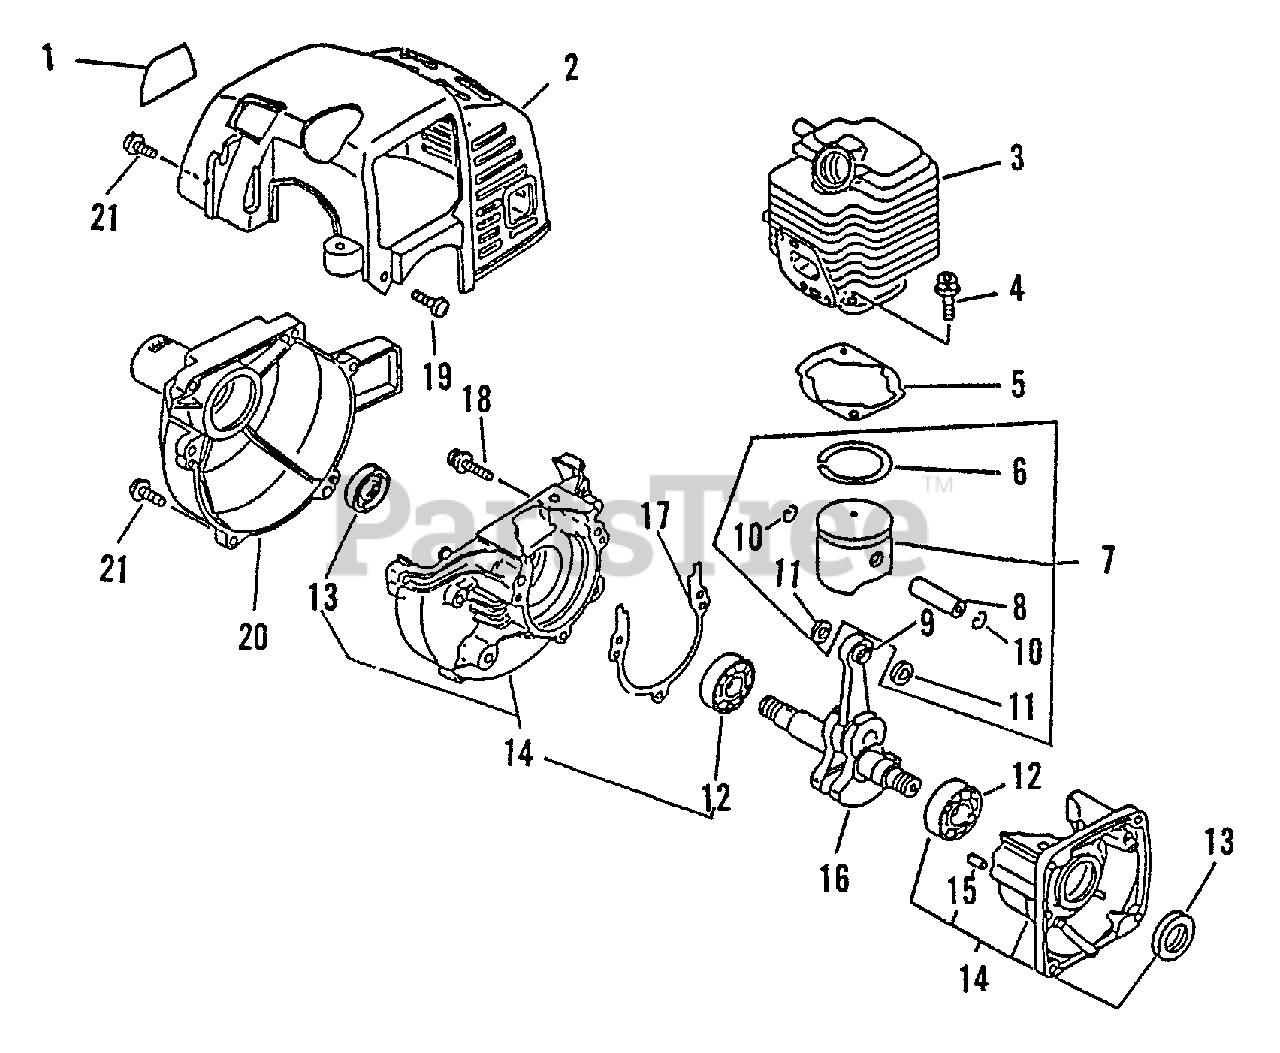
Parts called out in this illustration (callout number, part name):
1	Label, Model
2	Cover, Cylinder
3	Cylinder
4	Bolt, H.S. 5x22
5	Gasket, Cylinder Base
6	Ring, Piston
7	Piston kit
8	Pin, Piston
9	Bearing, Needle
10	Circlip, piston pin
11	Spacer, Piston pin
12	Bearing, ball 6201
13	Oil seal
14	Crankcase kit
15	Pin, Dowel
16	Crankshaft
17	Gasket, Crankcase
18	Screw 5x28
19	Screw 4x12
20	Cover, Pin
21	Screw 4x16
